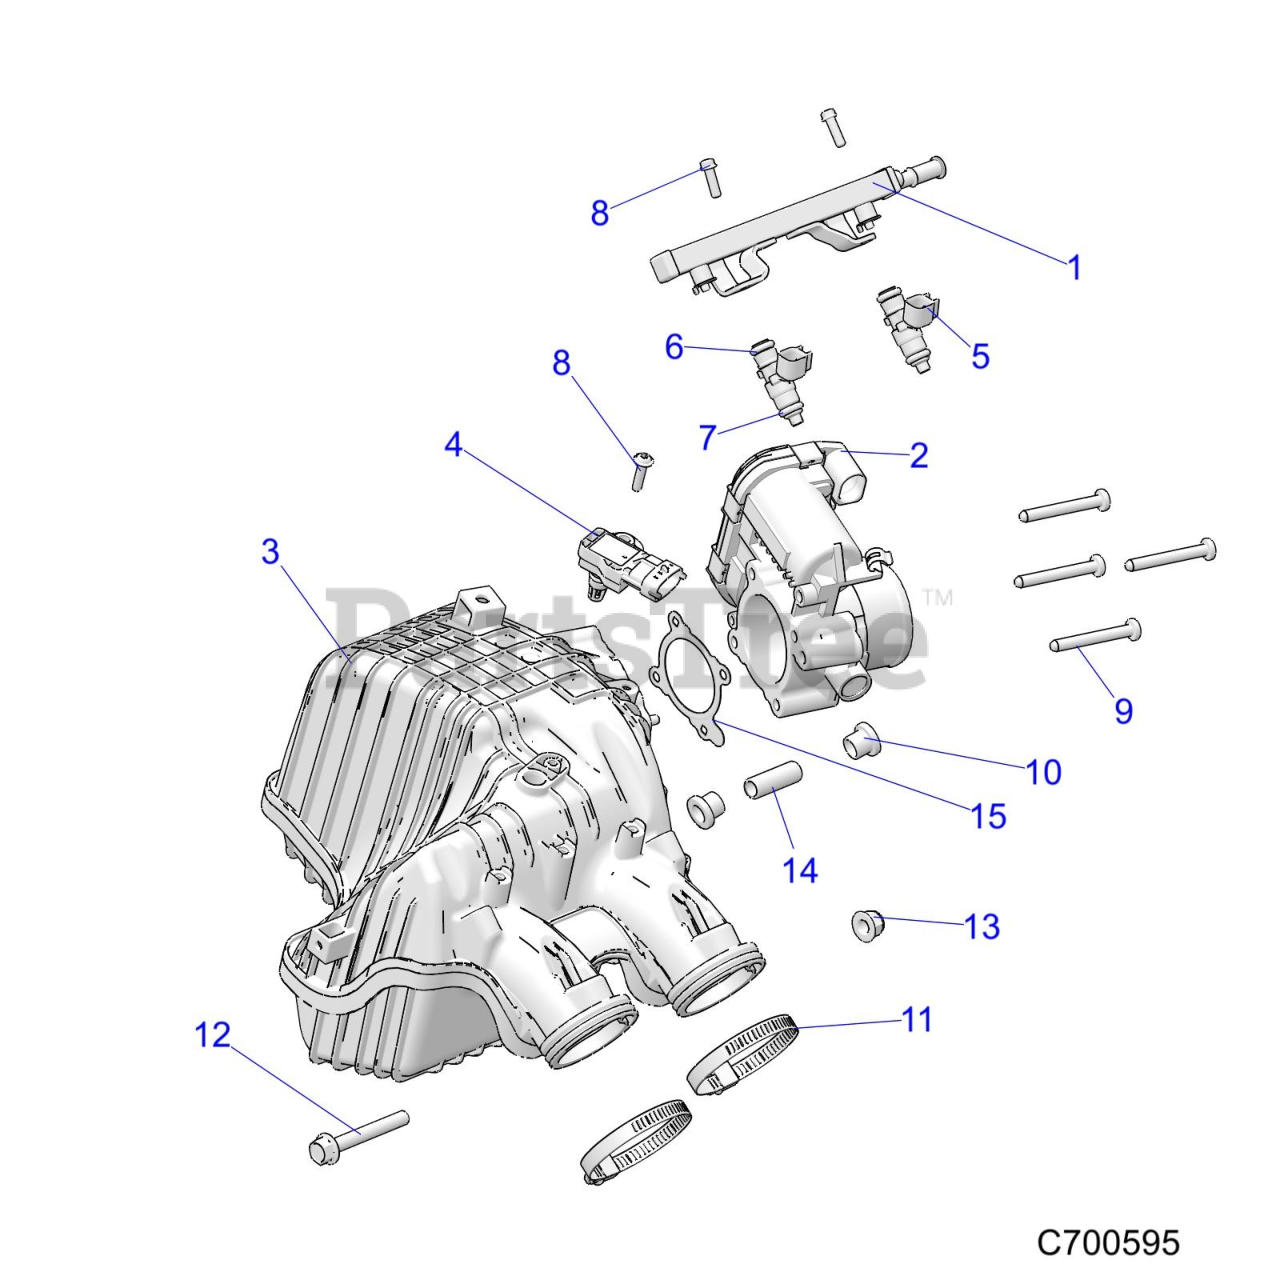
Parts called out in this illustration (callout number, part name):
1	RAIL-FUEL,SOHC
2	THROTTLE-ETC,46MM
3	MANIFOLD-INTAKE,SOHC
4	SENSOR-TMAP DSS3-TF
5	INJ-FUEL,SE
6	O-RING BOSCH,EV-SE,UPPER
7	O-RING BOSCH,EV-SE,LOWER
8	SCR-M6X20,HXFLG,0600214
9	SCR-M6X1.0X50.0 HX/FL-YD (10)
10	BUSHING-MOUNT
11	CLAMP,BAND,NARROW (10)
12	SCR-HXFL-M8X1.25X60 8.8 ZOD
13	NUT-M8X1.25,FLG,NYLOC-OLIVE D
14	SHAFT-COMPRESSION LMTR,34.4MM
15	GASKET-ETC
